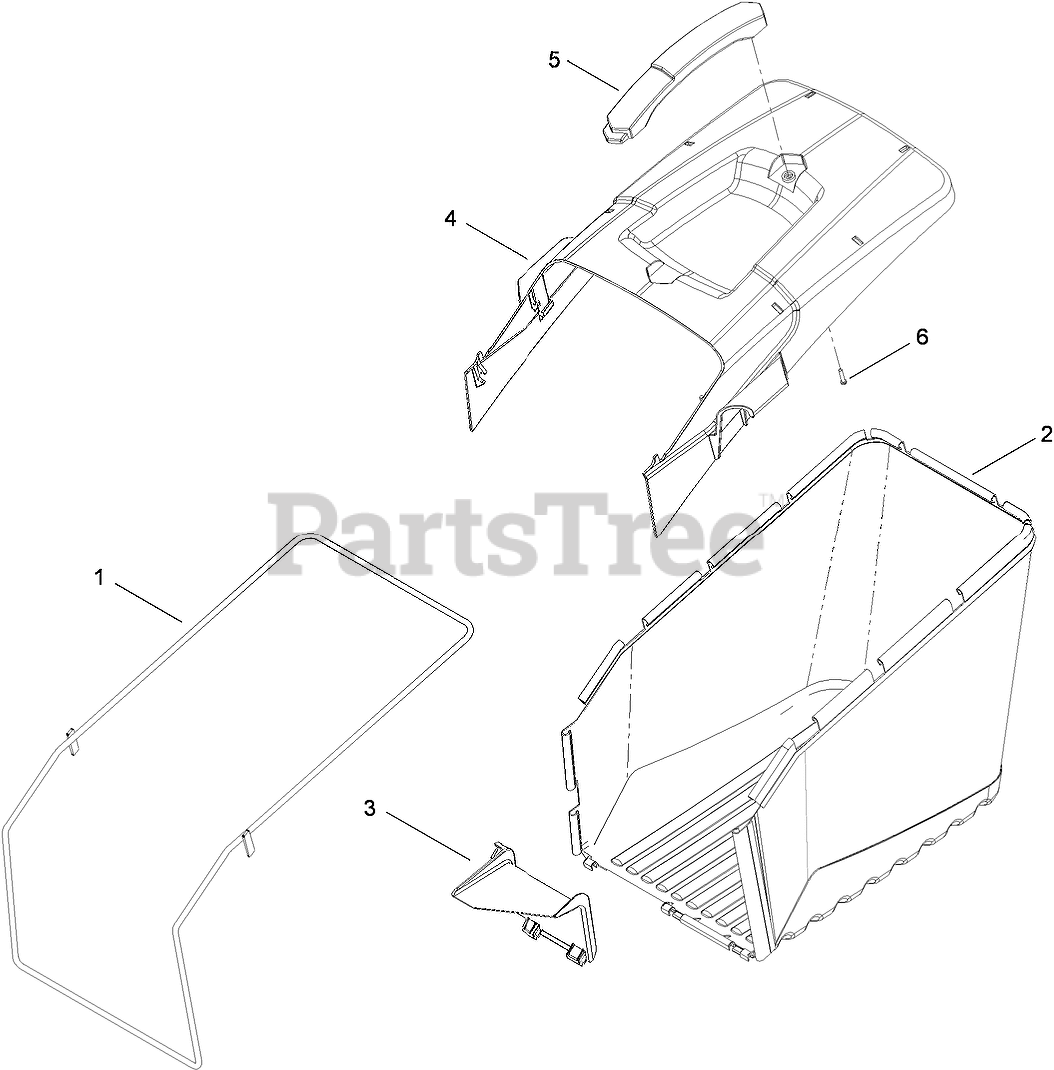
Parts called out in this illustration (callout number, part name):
1	BAG FRAME ASM
2	LOWER BAG ASM
3	LIP-BAG, GRASS
4	COVER-BAG
5	HANDLE-BAG
6	SCREW-BUTTON HEAD, TORX
